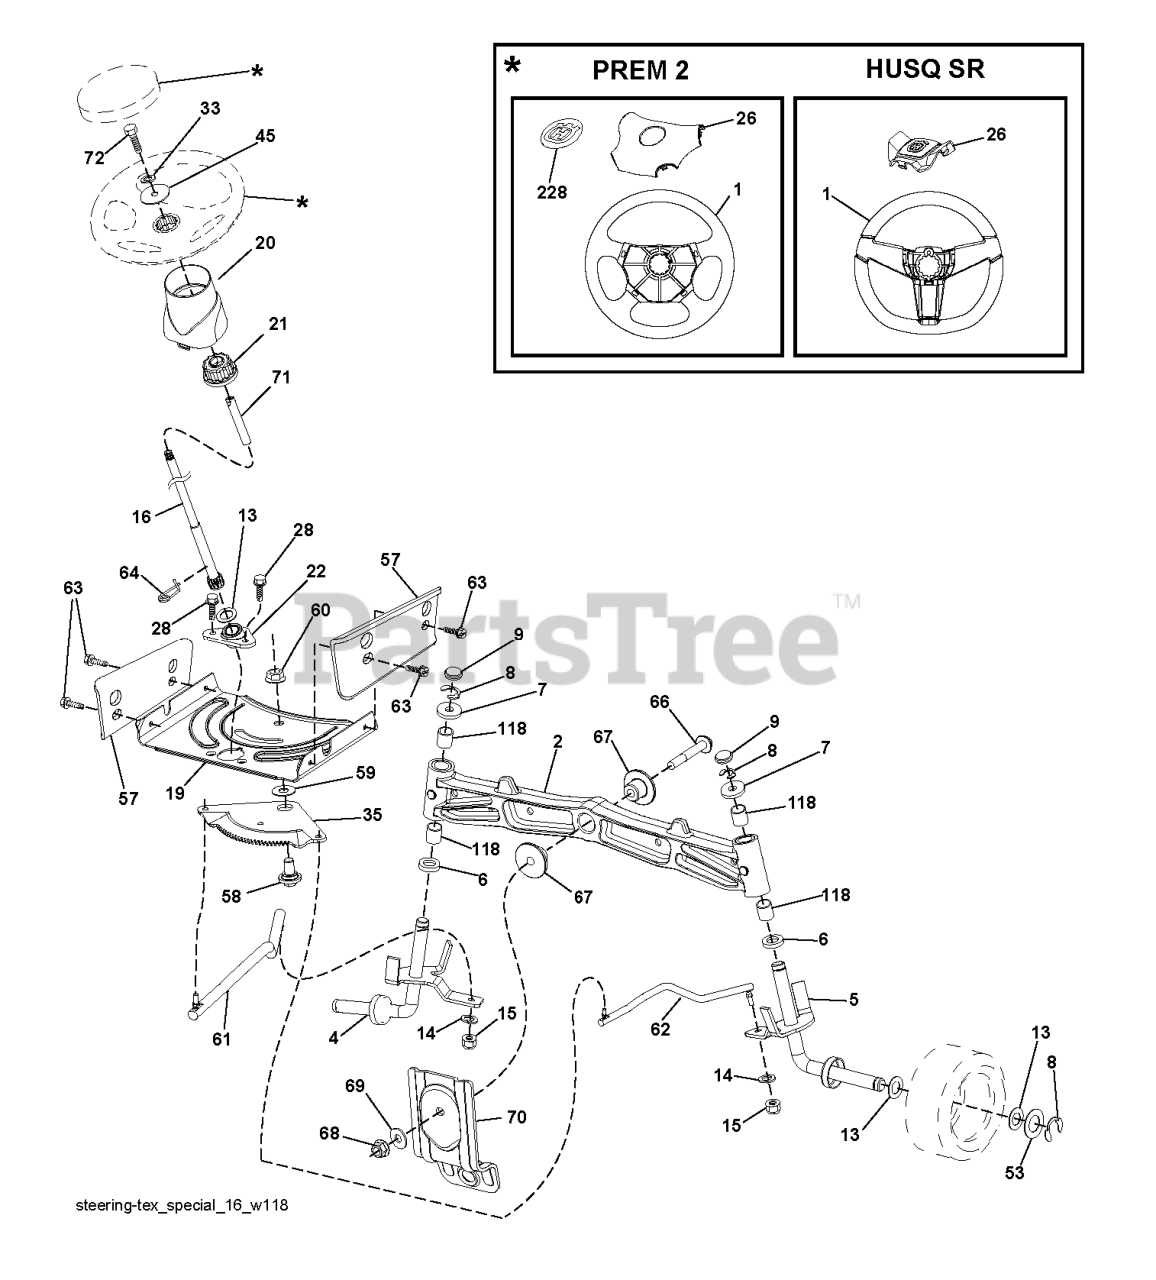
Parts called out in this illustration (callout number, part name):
1	RP WHEEL.STEER.HUSQ.PREM.OVMLD
2	AXLE.SVC.ASM CAST IRON.TEX
4	SPINDLE.WELDED.LH.15"TEX
5	SPINDLE.WELDED.RH.15"T
6	THRUST WASHER
9	CAP.SPINDLE.BLACK
14	WASHER, LOCK 3/8
15	NUT CROWNLOCK 3/8-24
16	SHAFT STEERING
19	PLATE.STEER.DDL.NLT/NG
20	BOOT, STEERING
21	ADAPTER, WHEEL STNG..
22	BUSHING.ASM.STEERING.A
26	RP INSERT.CAP.WHL.STRG.HUSQ.
28	SCREW, 3/8-16X3/4
33	WASHER.LOCK.HVY.HLCL.SPR.5/16
35	GEAR.SECTOR.PLATE.DDL.
45	WASHER.11/32
53	WASHER.HARDENED
57	BRACKET.UPSTOP.TEX
58	BOLT.SHOULDER.SECTOR.P
59	WASHER.THURST.SECTOR.S
60	NUT FLANGE LOCK 5/8-11
61	DRAGLINK.LH.BALLSTUD.D
62	DRAGLINK.RH.BALLSTUD.D
63	SCREW
64	RETAINER.CLIP.SPRING.S
66	BOLT HEX FGHD 7/16-14 X 3 SERR
67	BUSHING.PM.FRONT AXLE
68	NUT.LOCK.FLANGE.7/16
69	WASHER.1.5X.505X.118
70	BRKT.DECK.SUSPENSION.F
71	SHAFT EXTENSION STEERING
72	BOLT YT
118	BUSHING, AXLE CAST
228	DECAL.WHEEL.STRG.LGN.H
